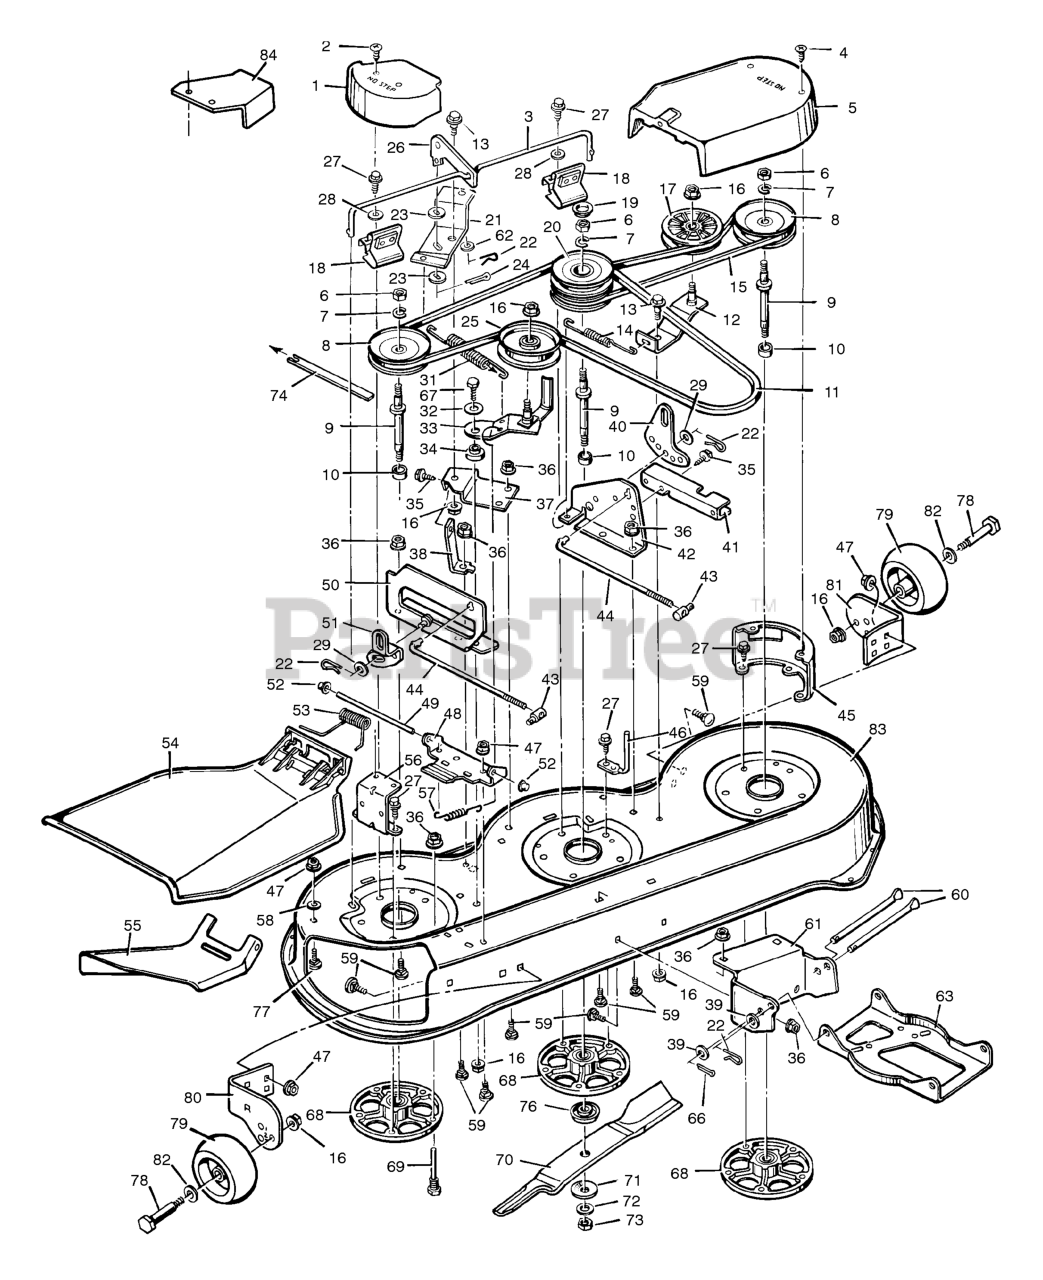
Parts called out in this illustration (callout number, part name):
1	Cover, Pulley
3	Rod, Brake
5	Cover, Left Pulley
6	Nut, Hex
7	Lockwasher
9	Jackshaft
10	Spacer, Bearing
11	Belt, Primary Mower Drive
12	Bracket, Idler
13	Bolt, Shoulder
14	Spring, Extension
15	Belt, Secondary Mower Drive
16	Locknut
17	Pulley, Idler
18	Spring Assembly, Brake
20	Pulley, Stack
21	Bracket, Pivot
22	Pin, Hair
24	Pin, Cotter
25	Pulley, Idler
26	Link, Brake
31	Spring, Extension
33	Bracket, Idler
34	Bushing
36	Nut, Hex
37	Support, Pivot
38	Strut, Pivot
40	Plate, Adjuster
41	Channel, Left Cover
42	Bracket Assembly, Lifter
43	NUT, Adjusting, 1/2-13
44	Rod, Adjuster
45	Bracket, Left Cover
46	Guide, Belt
47	Locknut
48	Bracket, Hinge
49	Rod, Deflector
50	Bracket Assembly, Lifter
51	Link, Suspension
52	Push- On Cap
53	Spring, Torsion
54	Deflector
55	Deflector, Inside
56	Bracket, Cover
57	Spring, Extension
58	Washer
59	Bolt, Carriage
60	Rod, Hanger
61	Bracket, Front Hanger
63	Hanger, Front
66	Pin, Cotter
67	Bolt, Hex
68	Housing, Mandrel
69	Guide, Belt
70	Blade (3 required)
71	Washer, Belleville
73	Nut, Hex
74	Indicator, Plastic
76	Adapter, Blade
77	Bolt, Carriage
78	BOLT, Gauge Wheel
79	Wheel, Gauge
80	Bracket, Right Gauge Wheel
81	Bracket, Left Gauge Wheel
82	Washer
83	Housing, Mower
